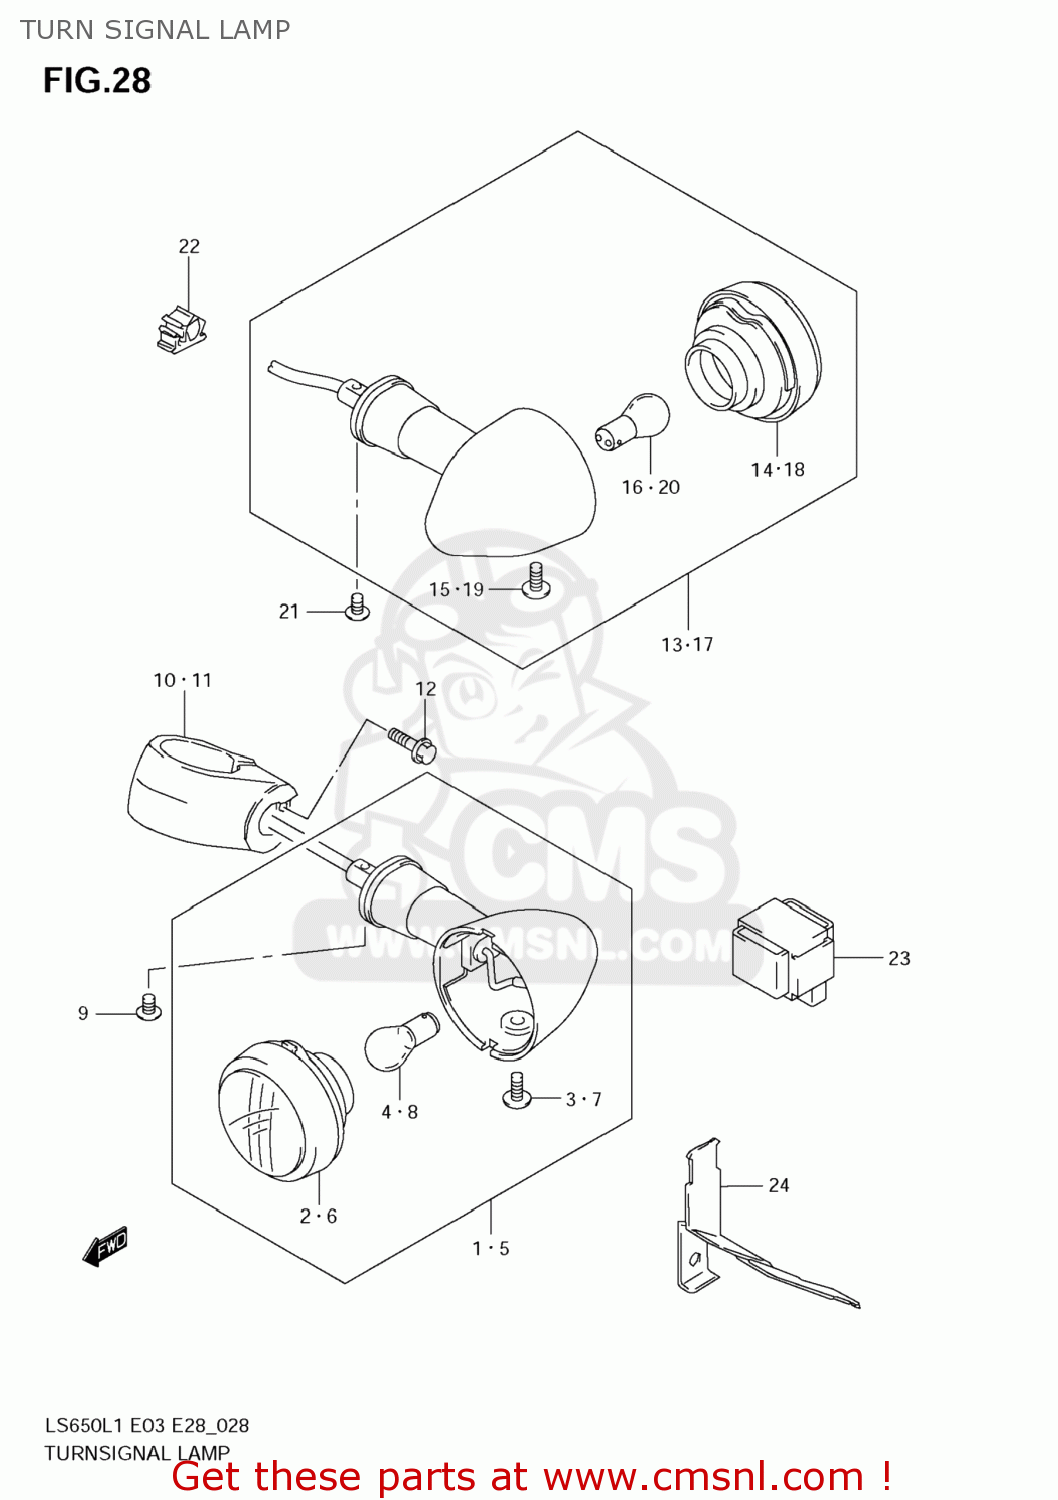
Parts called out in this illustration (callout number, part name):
1	LAMP ASSY,FR TURN SIGNAL,R
2	LENS
3	SCREW(4X10)
4	BULB(12V21/5W)
5	LAMP ASSY,FR TURN SIGNAL,L
6	LENS
7	SCREW(4X10)
8	BULB(12V21/5W)
9	SCREW
10	BRACKET,FR TURNSIGNAL LAMP,R
11	BRACKET,FR TURNSIGNAL LAMP,L
12	BOLT
13	LAMP ASSY,RR TURNSIGNAL,R
14	LENS
15	SCREW(4X10)
16	BULB(12V21W)
17	LAMP ASSY,RR TURNSIGNAL,L
18	LENS
19	SCREW(4X10)
20	BULB(12V21W)
21	SCREW
22	CLAMP
23	RELAY ASSY
24	BRACKET,TURNSIGNAL RELAY
